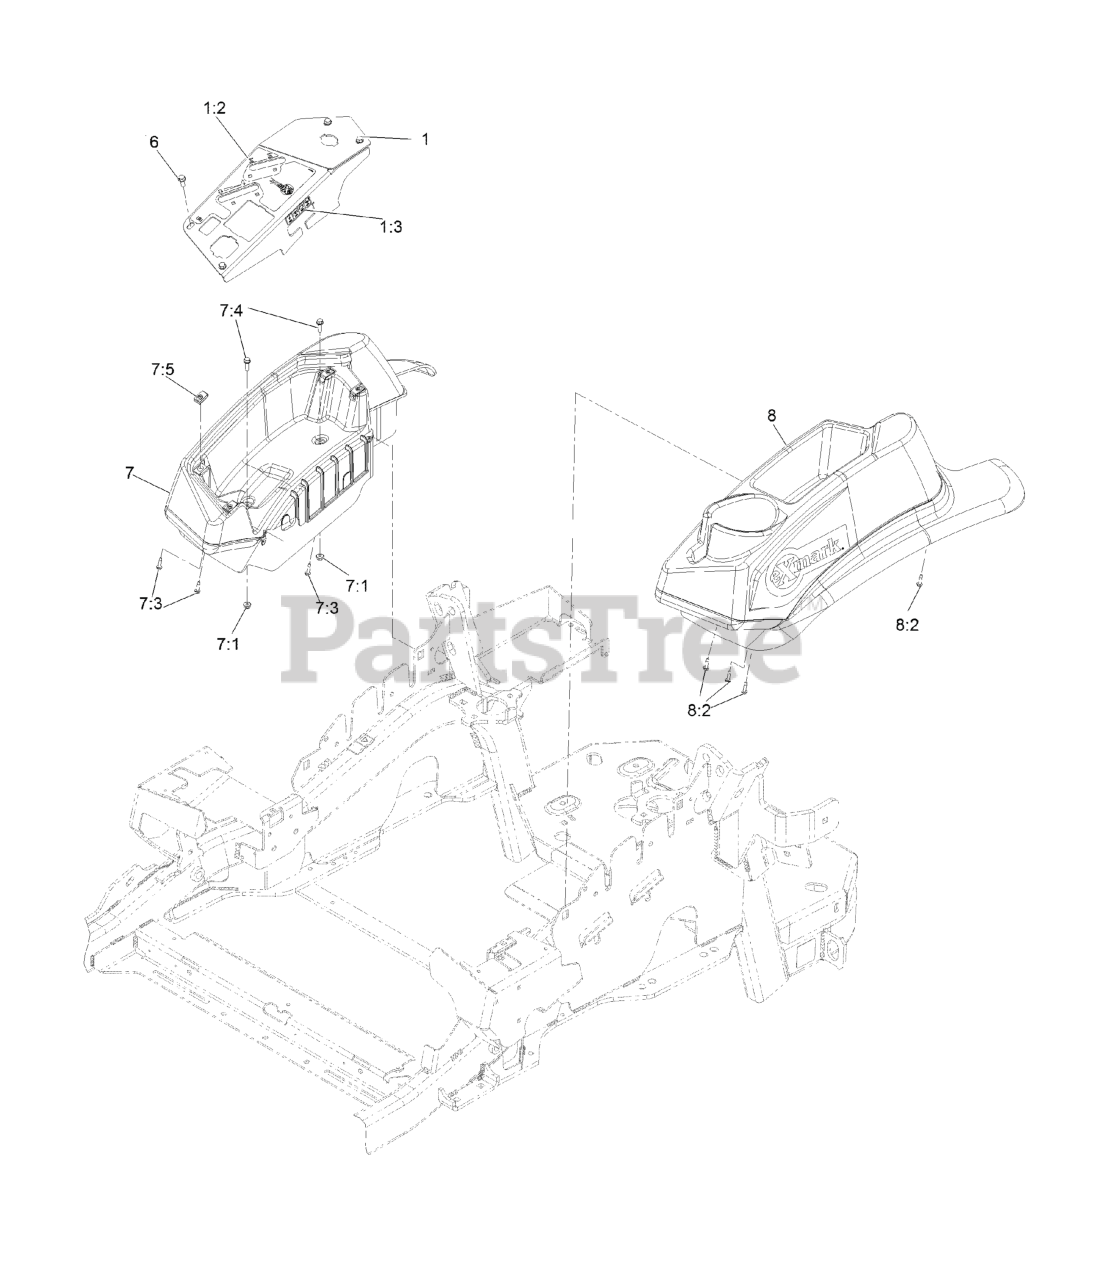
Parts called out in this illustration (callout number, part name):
1	ASM-PANEL, CONTROL W/DECAL
1:2	DECAL-CONTROL PANEL NON-EFI
1:3	DECAL-FUSES
6	SCREW-HWH
7	CONSOLE,RH NARROW ASM
7:3	SCREW,THD FORM,HWH
7:4	SCREW-HWH
8	CONSOLE.LH NARROW ASM
8:2	SCREW,THD FORM,HWH
